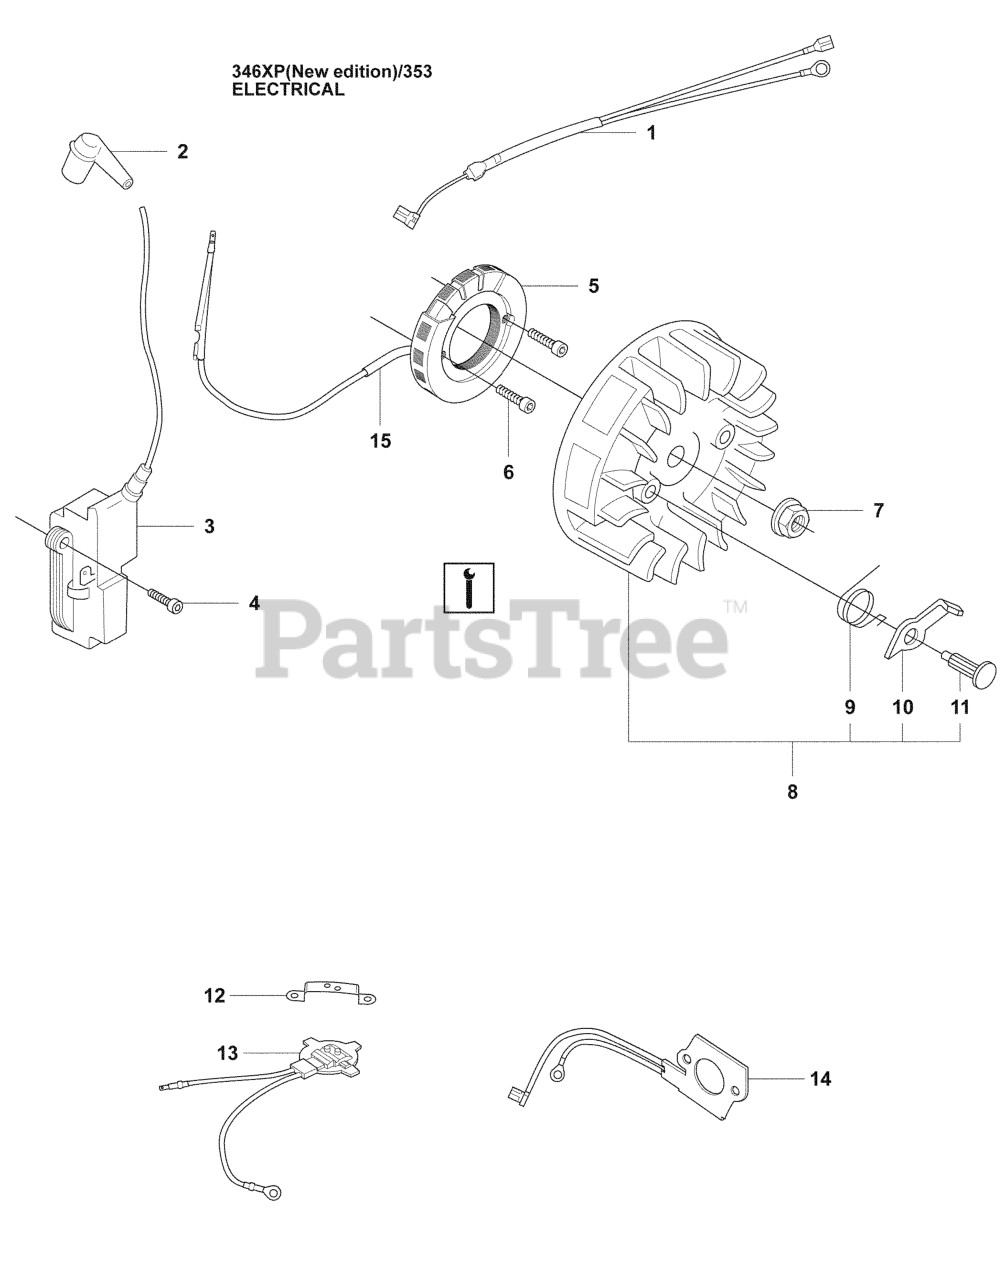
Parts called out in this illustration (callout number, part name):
1	WIRING ASSY
1	WIRING ASSEMBLY
2	SPARK PLUG CONN. KIT
3	%IGNITION MODULE
5	GENERATOR
5	GENERATOR STATOR
7	NUT W/ WASHER
8	FLYWHEEL
8	FLYWHEEL (G)
8	RP FLYWHEEL
9	%SPRING, STARTER CATCH
10	PAWL
11	RIVET
12	RETAINER
13	THERMOSTAT ASSY
14	HEATING PLATE
15	CABLE COVER
